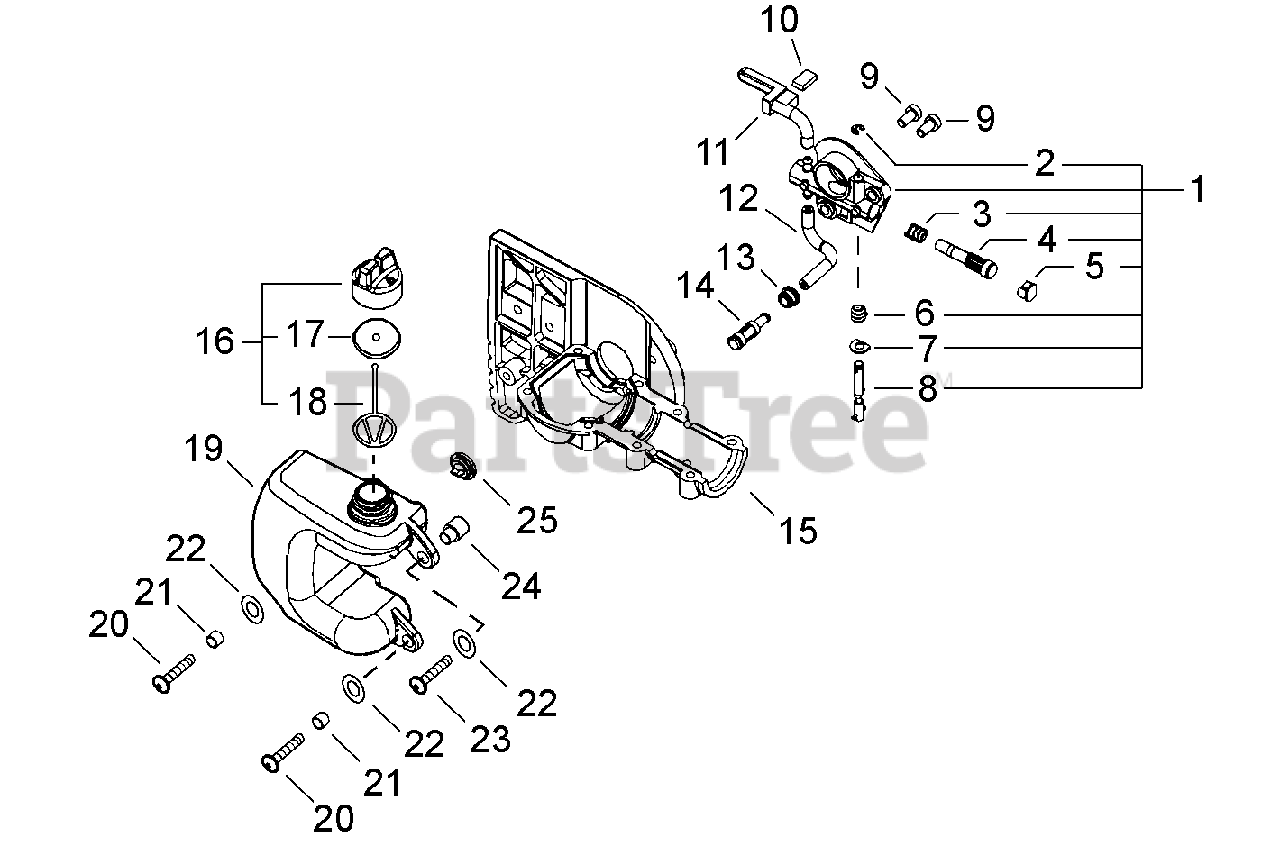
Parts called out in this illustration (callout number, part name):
1	AUTO-OILER ASSY
2	RING, RETAINING
4	PLUNGER ASSY
5	CAP, OIL PUMP
8	ADJUSTER, OILER
9	SCREW - 5X10
10	PAD, FOAM
11	TUBE, OIL OUTLET
12	PIPE - 3X6X75 -- BLACK
13	GROMMET
14	FILTER, OIL
15	GEAR CASE ASSY - LOWER
16	CAP ASSY
17	GASKET, CAP
18	CONNECTOR, CAP
19	TANK, OIL
20	SCREW - 5X16
22	WASHER - 5
23	SCREW - 4X25
24	COLLAR - 6
